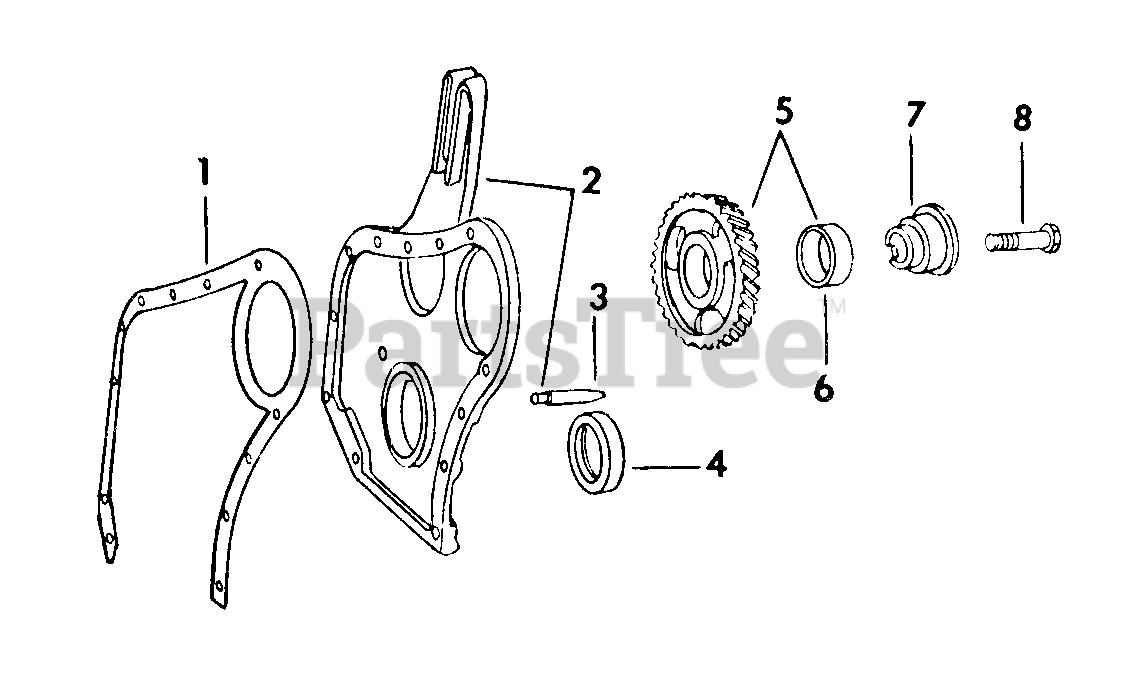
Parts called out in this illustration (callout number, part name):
1	CRANKCASE FRONT COVER
2	COVER ASSY, CRANKCASE FRONT
3	POINTER, TIMING
4	SEAL W/RING, CRANKCASE FRONT COVER
5	GEAR
6	BUSHING, IDLER GEAR
7	SHAFT, IDLER GEAR
8	BOLT, IDLER GEAR SHAFT
